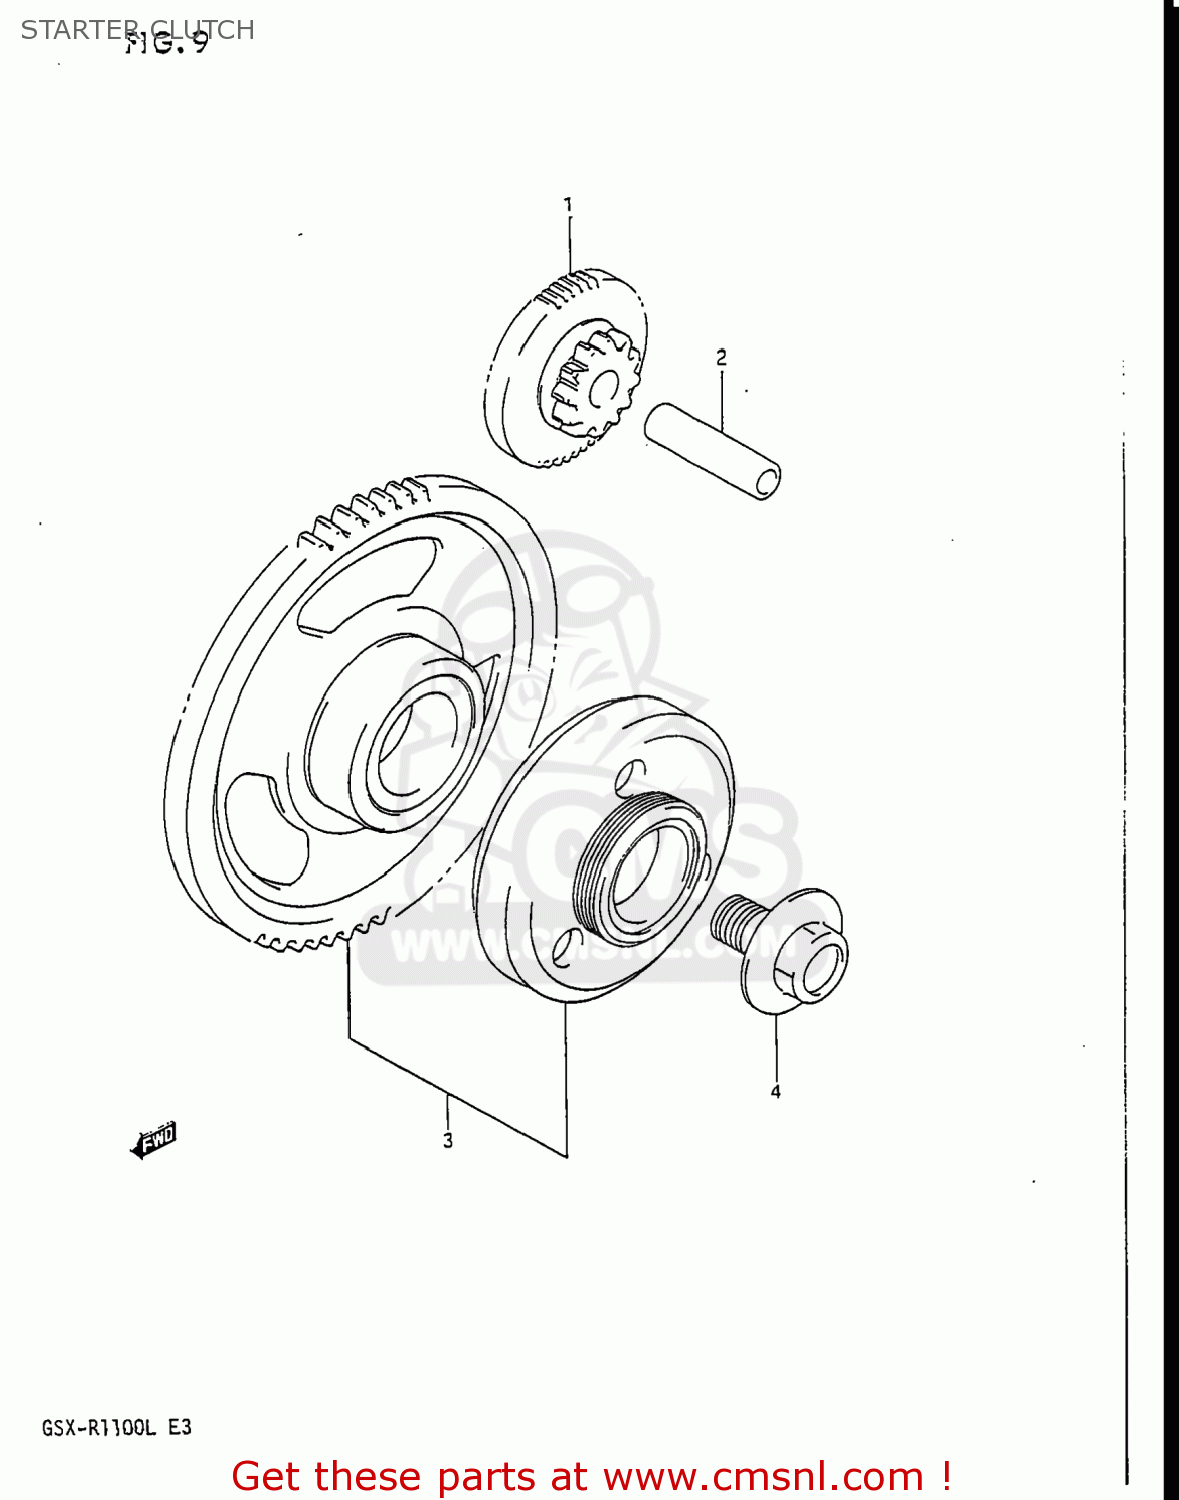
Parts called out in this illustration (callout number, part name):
1	GEAR,STARTER IDLE(NT:12,53)
2	PIN(7X11X42)
3	CLUTCH SET,STARTER
4	BOLT(14X21)
